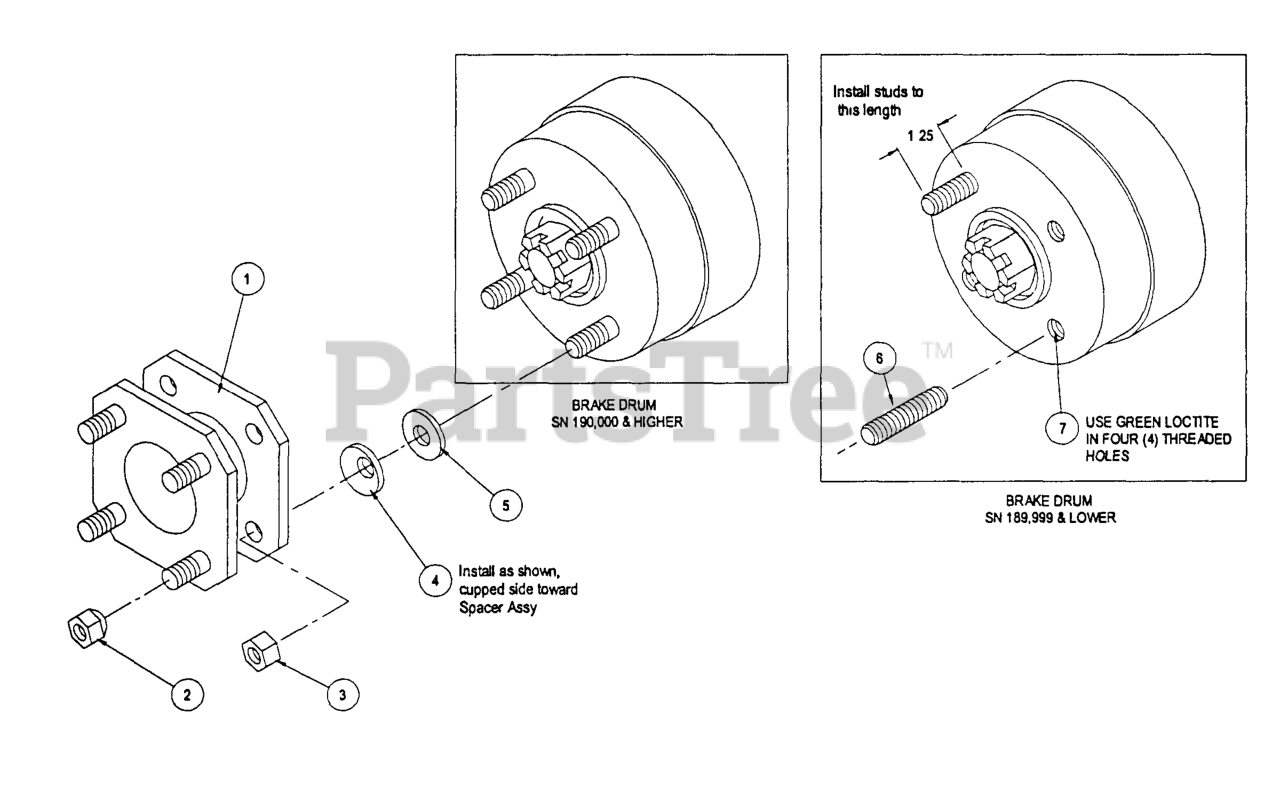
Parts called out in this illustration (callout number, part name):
3	Nut, Hex 1/2-20
4	WASHER-SPRING
6	STUD PLTD
7	PRO-LOCK-RETAINING 1
